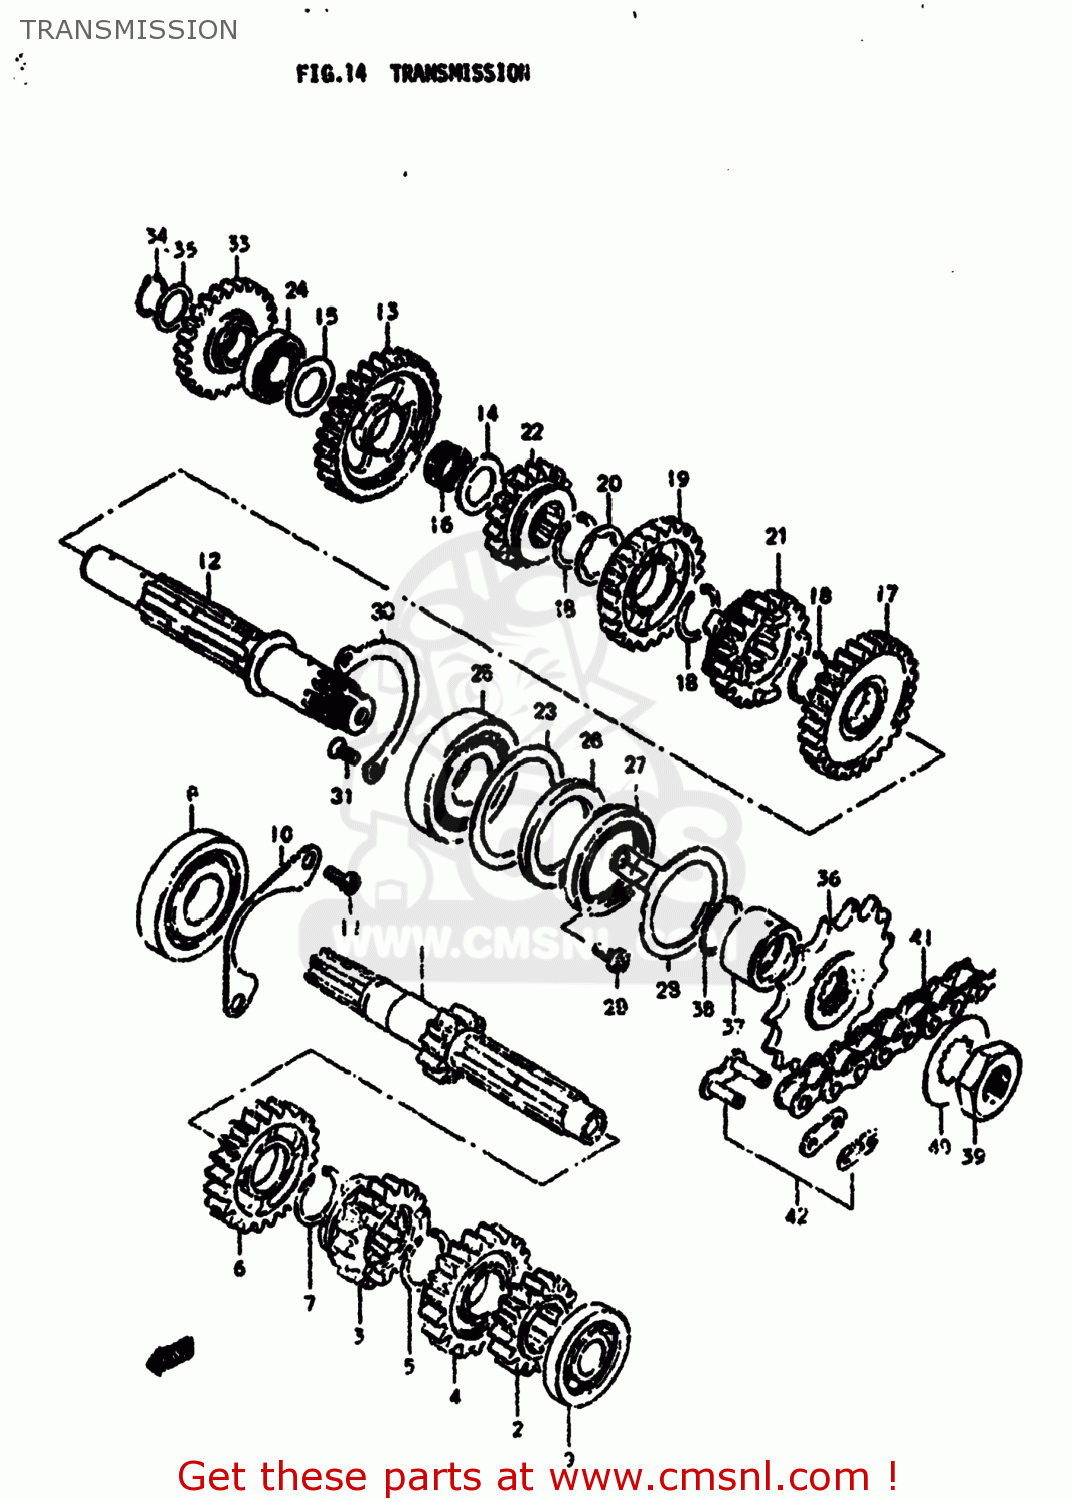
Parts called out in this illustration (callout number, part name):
1	SHAFT,COUNTER
2	GEAR,SECOND DRIVE
3	GEAR,THIRD DRIVE
4	GEAR,FOURTH DRIVE
5	CIRCLIP
6	GEAR,FIFTH DRIVE
7	CIRCLIP
8	BEARING
9	BEARING
10	PLATE,COUNTERSHAFT BEARING
11	SCREW 6X12
12	SHAFT,DRIVE
13	GEAR,1ST DRIVEN(NT:29)
14	WASHER
15	WASHER
16	BEARING(17X21X9.8)
17	GEAR,SECOND DRIVEN
18	CIRCLIP
19	GEAR,THIRD DRIVEN
20	WASHER,LOCK
21	GEAR,FOURTH DRIVEN
22	GEAR, 5TH DRIVEN NT:18
23	WASHER
24	BEARING(17X36X12)
25	BEARING(22X56X16)
26	OIL SEAL (30X47X5)
27	SEAL,OIL(30X47X7)
28	PLATE,DRIVESHAFT OIL
29	SCREW 6X12
30	RETAINER,DRIVE SHAFT BEARING
31	SCREW
33	GEAR,KICK STARTER IDLER(NT:25)
34	CIRCLIP
35	WASHER
36	SPROCKET,ENGINE
37	SPACER,ENGINE SPROCKET
38	O RING(D:2.5,ID:21)
39	NUT
40	WASHER,LOCK
41	CHAIN ASSEMBLY,DRIVE
42	JOINT ASSEMBLY,CHAIN
